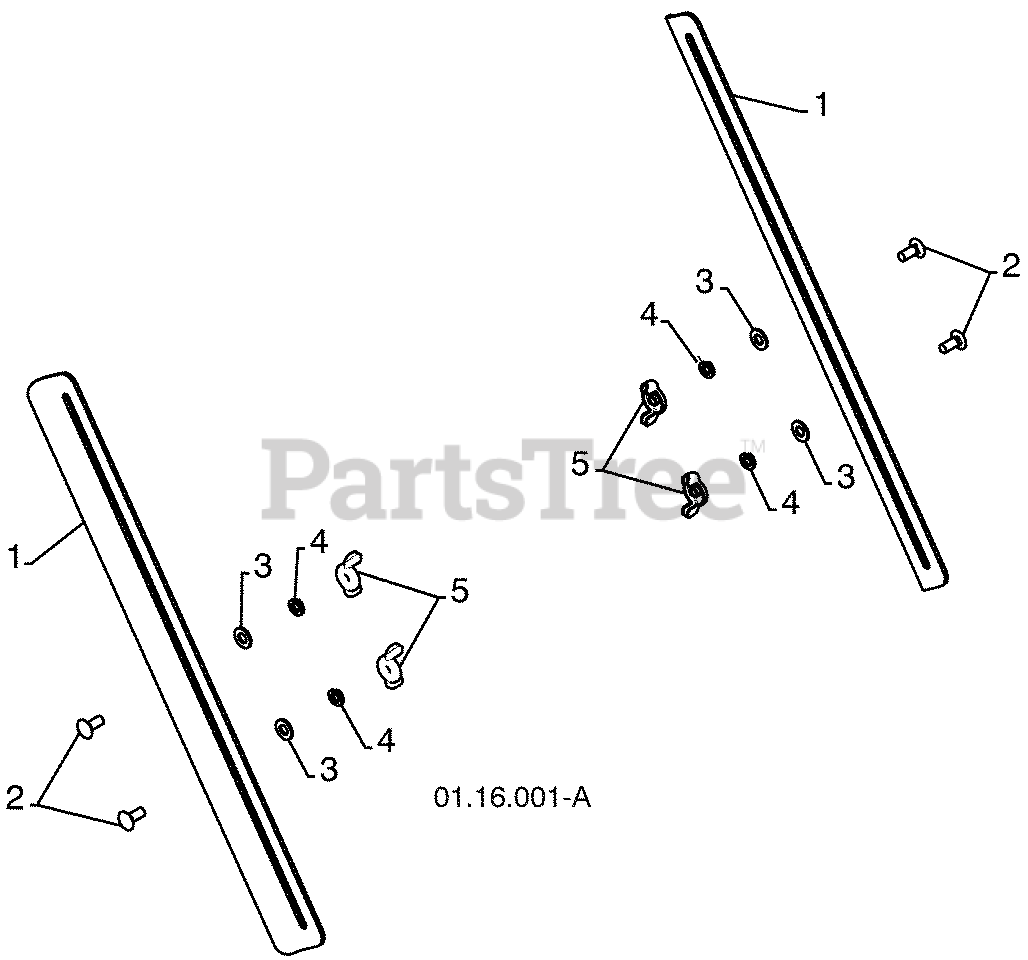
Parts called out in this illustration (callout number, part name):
1	DRIFT CUTTER BAR
2	CARRIAGE BOLT 5/16-18 X .750
3	PLASTIC WASHER
4	LOCKWASHER 5/16
5	NUT 5/16-18
